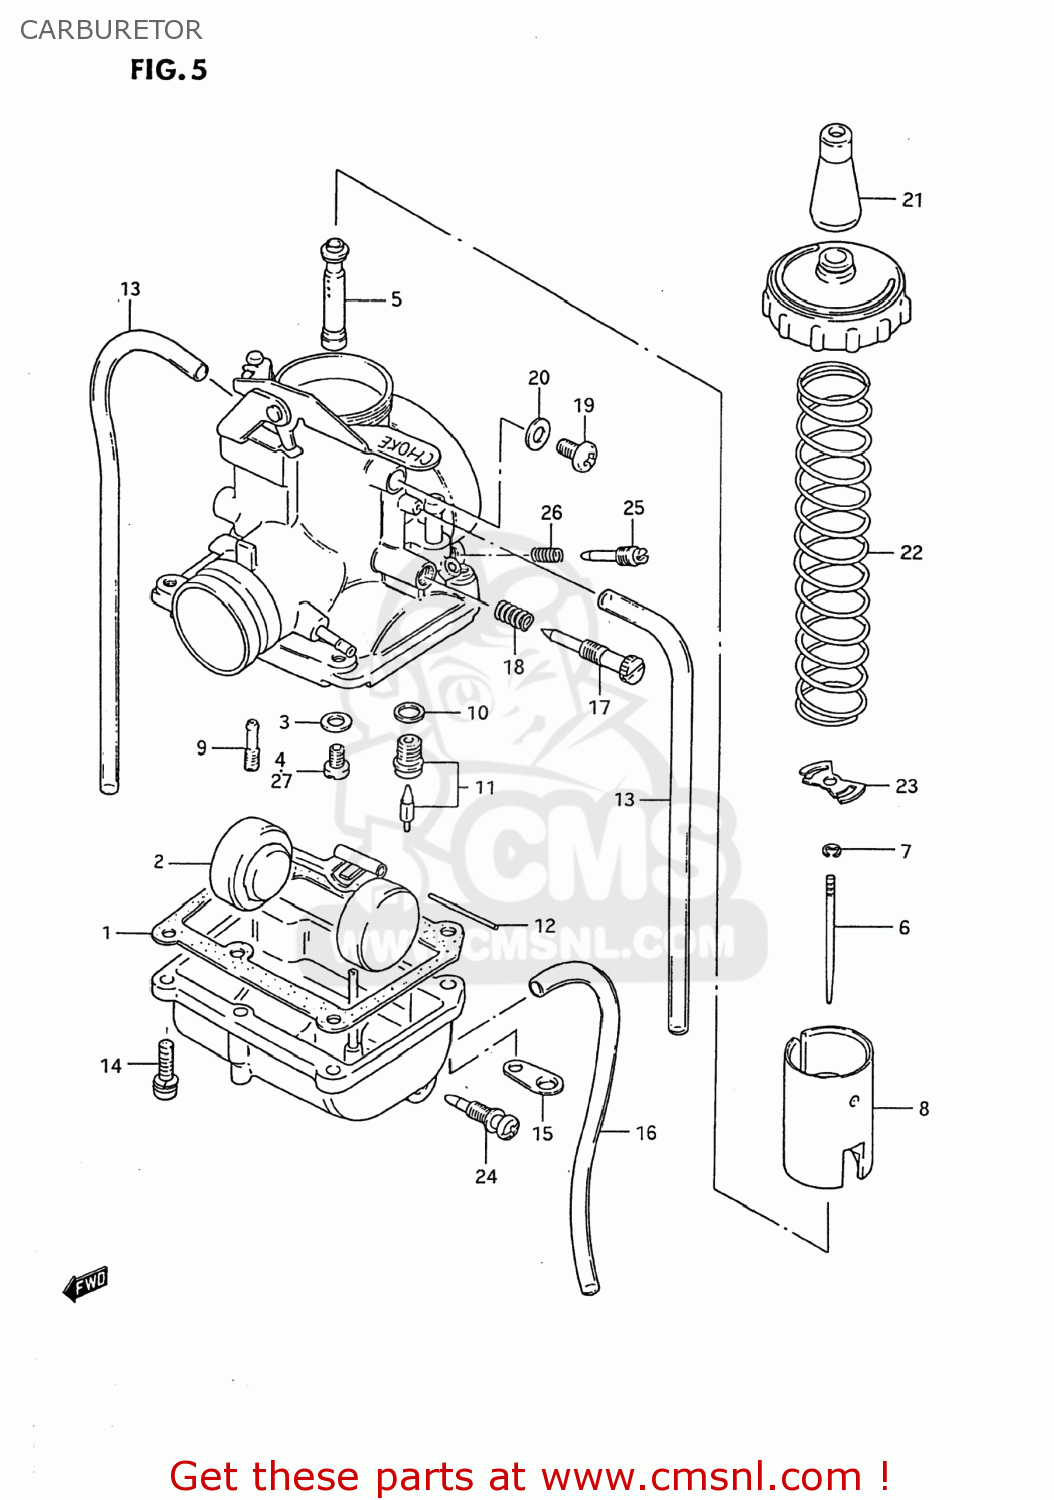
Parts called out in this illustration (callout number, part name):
1	GASKET,FLOAT CHAMBER (NAS)
2	FLOAT
3	WASHER,NEEDLE NOZZLE
4	JET,MAIN(87.5)
5	JET,NEEDLE
6	NEEDLE,JET
7	CLIP
8	VALVE,THROTTLE
9	JET,PILOT(25)
10	GASKET,NEEDLE VALVE (NAS)
11	VALVE ASSY,NEEDLE
12	PIN,FLOAT
13	HOSE
14	SCREW
15	PLATE
16	HOSE(3X5X650)
17	SCREW,THROTTLE STOP
18	SPRING
19	SCREW
20	GASKET,DRAIN PLUG (NAS)
21	CAP,CABLE ADJUSTER
22	SPRING,THROTTLE VALVE
23	STOPPER,NEEDLE CLIP
24	PLUG,DRAIN
25	SCREW,PILOT AIR
26	SPRING
27	JET,MAIN
